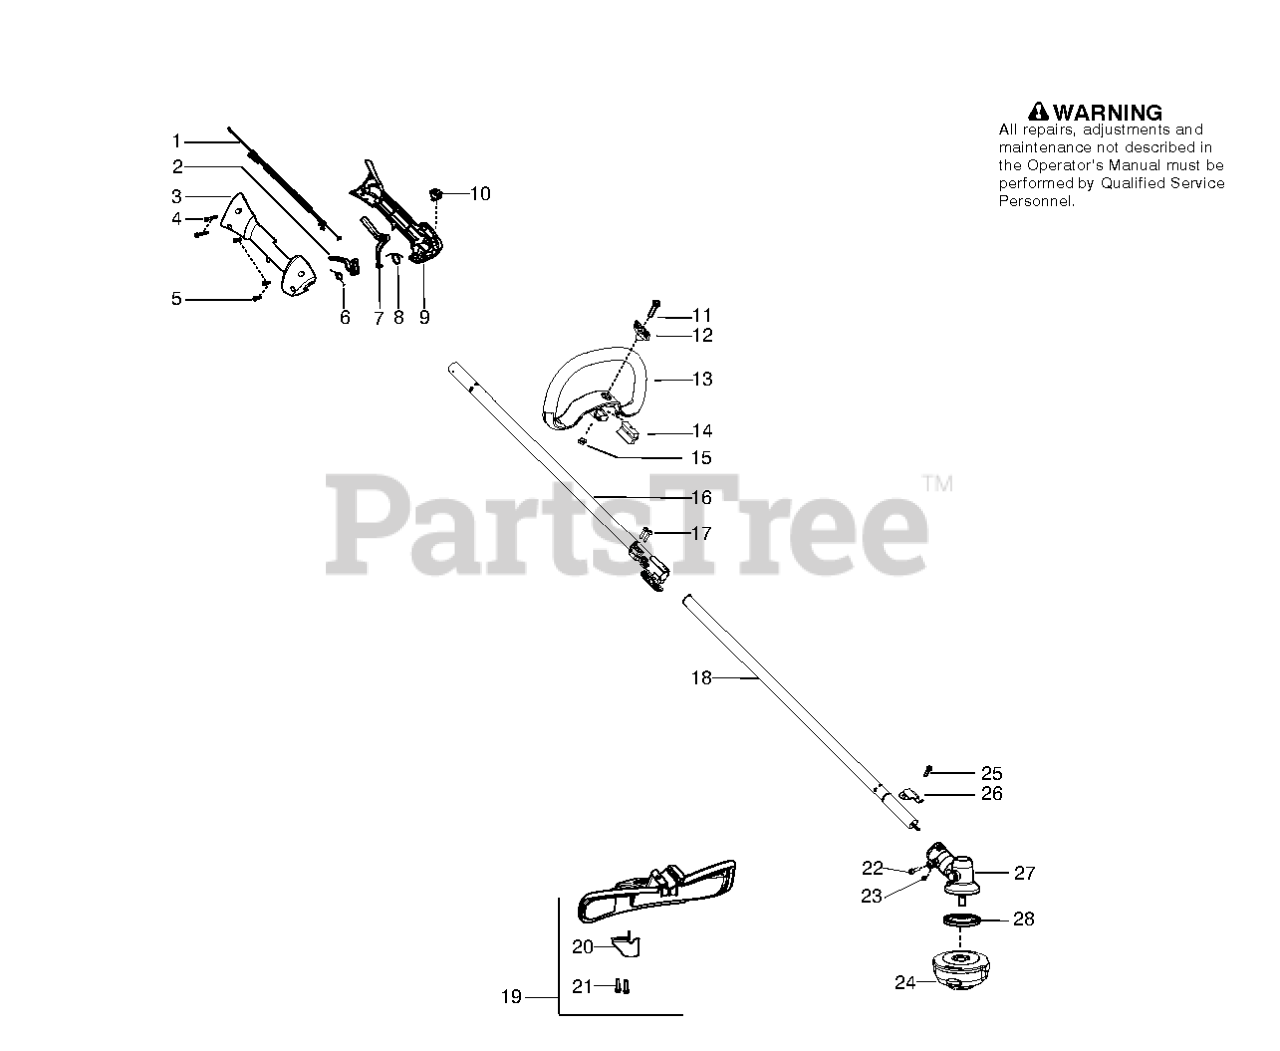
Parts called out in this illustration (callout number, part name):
4	CYLINDER COMPL/DEKO
5	SCREW M4 X 1.75 PT 16MM
6	SPRING TRIGGER
7	THROTTLE LOCKOUT
8	SPRING LOCKOUT
9	HSG THROTTLE LH
10	KIT SWITCH
11	SCREW M6X50
12	KNOB
13	ASSY LOOP HANDLE
14	SPACER PLASTIC
15	NUT
16	DRIVE SHAFT
18	KIT DRIVESHAFT LOWER LDX
19	KIT COBI SHIELD
20	Limiter - Line
22	SCREW - CARB. ADAPTOR
24	T25 10MM LH TRIMMER HEAD
25	SCREW 1/4-20 X 7/8 (TAP
26	BRACKET SHIELD STRAIGHT SHAFT
27	ASSY GEARBOX
28	DRIVE DISC
29	CYLINDER COMPL/DEKO
